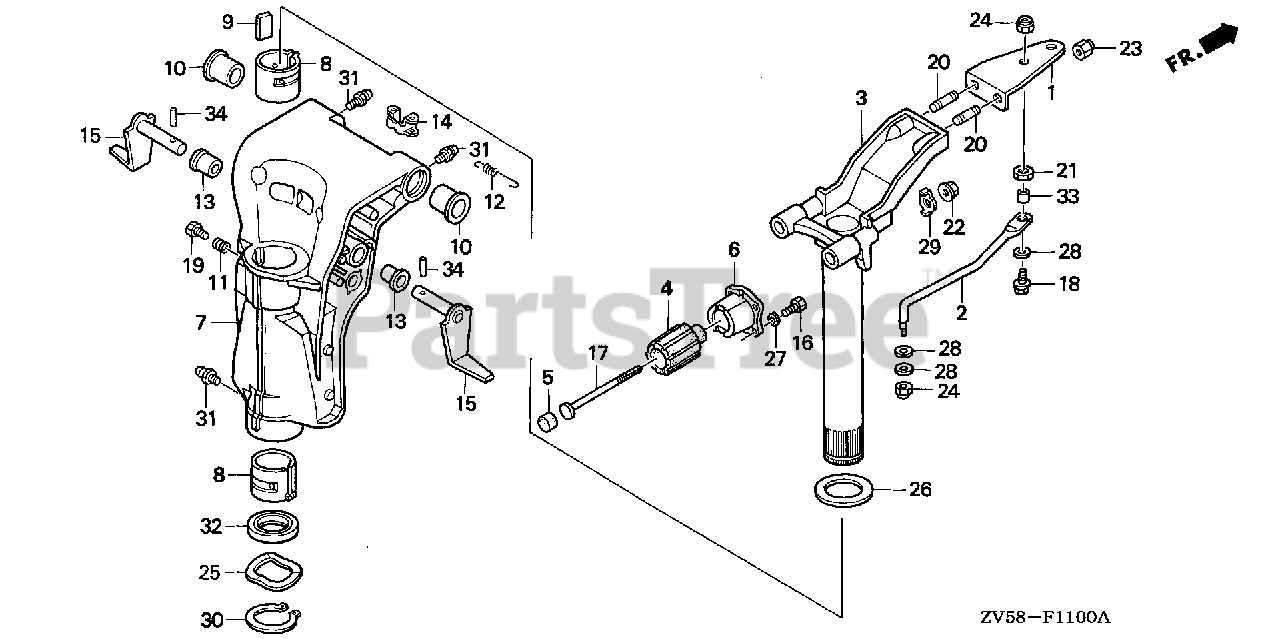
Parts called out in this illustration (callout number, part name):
1	PLATE, STEERING
2	ROD, STEERING
3	FRAME, MOUNTING *NH282MU* (OYSTER SILVER METALLIC-U) (NOT AVAILABLE)
4	RUBBER, MOUNTING (UPPER)
5	RUBBER, MOUNTING (UPPER) (B)
6	HOLDER, MOUNTING (UPPER) *NH8* (DARK GRAY)
7	CASE, SWIVEL *NH282MU* (OYSTER SILVER METALLIC-U)
8	LINER, SWIVEL CASE
9	BLOCK, FRICTION
10	BUSH, SWIVEL CASE
11	SPRING, FRICTION ADJUSTING
12	SPRING, TILT LEVER
13	BUSH, TILT ARM
14	BRACKET, TILTING
15	PLATE, TILT ARM
16	BOLT, HEX. (6X18)
17	BOLT, SPECIAL (10X130)
18	BOLT (3/8-24 UNF)
19	BOLT, SPECIAL (8X20)
20	BOLT, STUD (10X28)
21	NUT (3/8-24 UNF)
22	NUT, FLANGE (10MM)
23	NUT, SELF-LOCK (10MM)
24	NUT, SELF-LOCK (3/8-24UNF)
25	WASHER, WAVE (40MM)
26	WASHER, THRUST (34MM)
27	WASHER, PLAIN (6MM) Use up to Frame SN 4800342.
28	WASHER (10MM)
29	WASHER, SPECIAL
30	CIRCLIP (OUTER) (39MM)
31	NIPPLE, GREASE
32	OIL SEAL (39.5X52X6) (ARAI)
33	COLLAR, STEERING ROD
34	PIN, SPRING (2.5X20)
